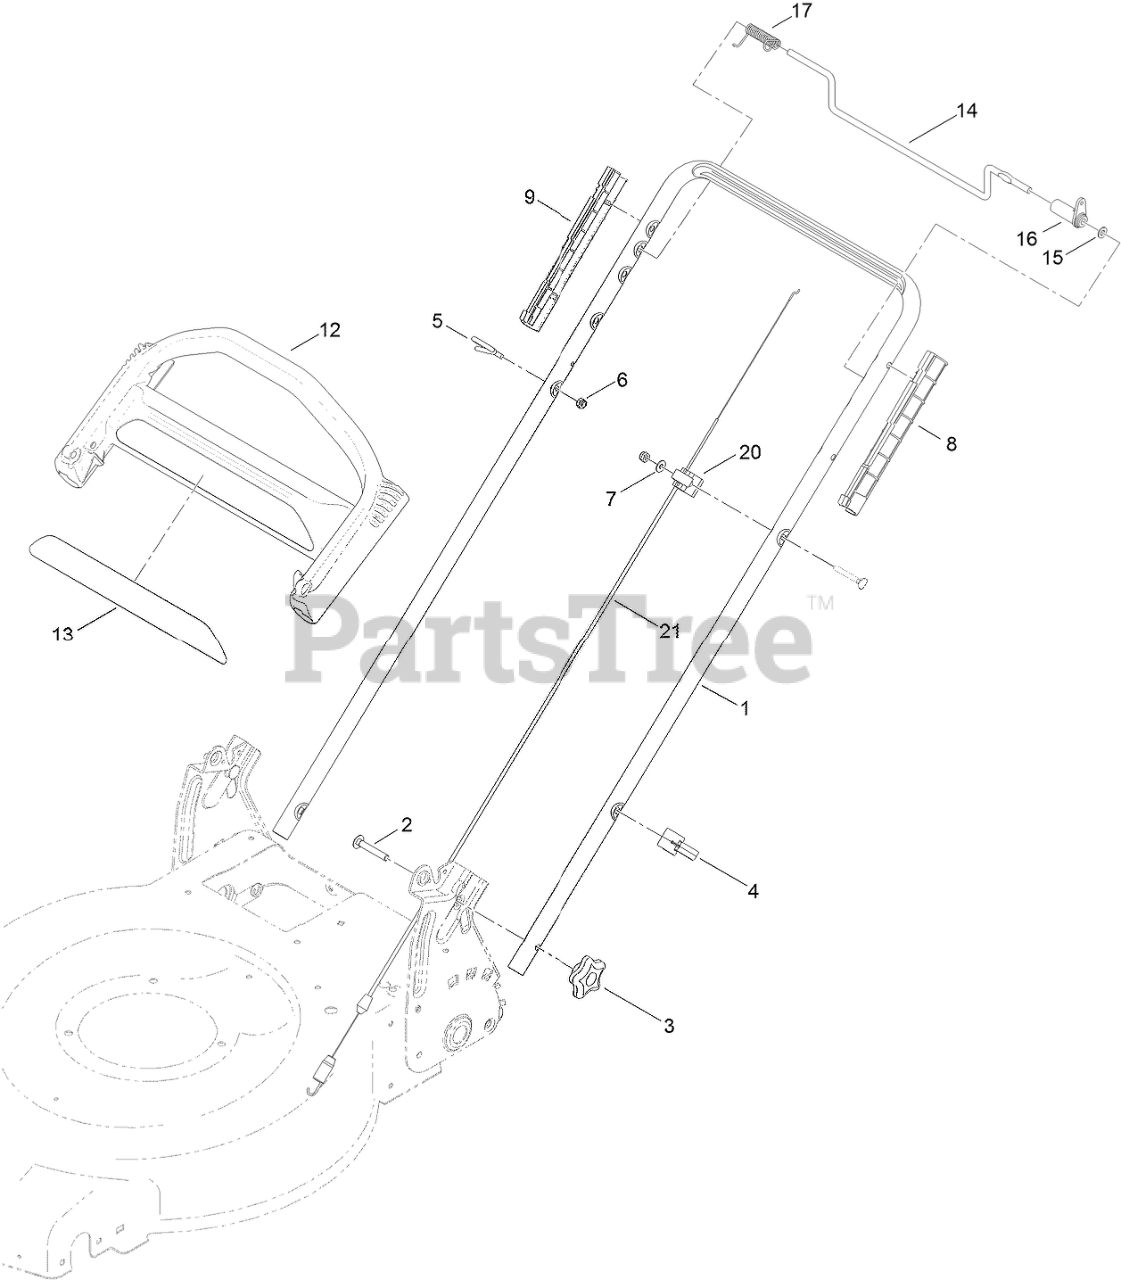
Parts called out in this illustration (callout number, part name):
2	Screw-CARR
3	KNOB-HANDLE
4	GUIDE-CABLE
5	GUIDE-ROPE
6	NUT-LOCK, NI
7	WASHER-FLAT
8	GUIDE-LH
9	GUIDE-RH
12	HANDLE-CONTROL
14	BAR-CONTROL, TRACTION
15	WASHER-PLAIN
16	LEVER-TRACTION
17	Spring-Torsion
20	ANCHOR-CABLE
21	CABLE-TRACTION
